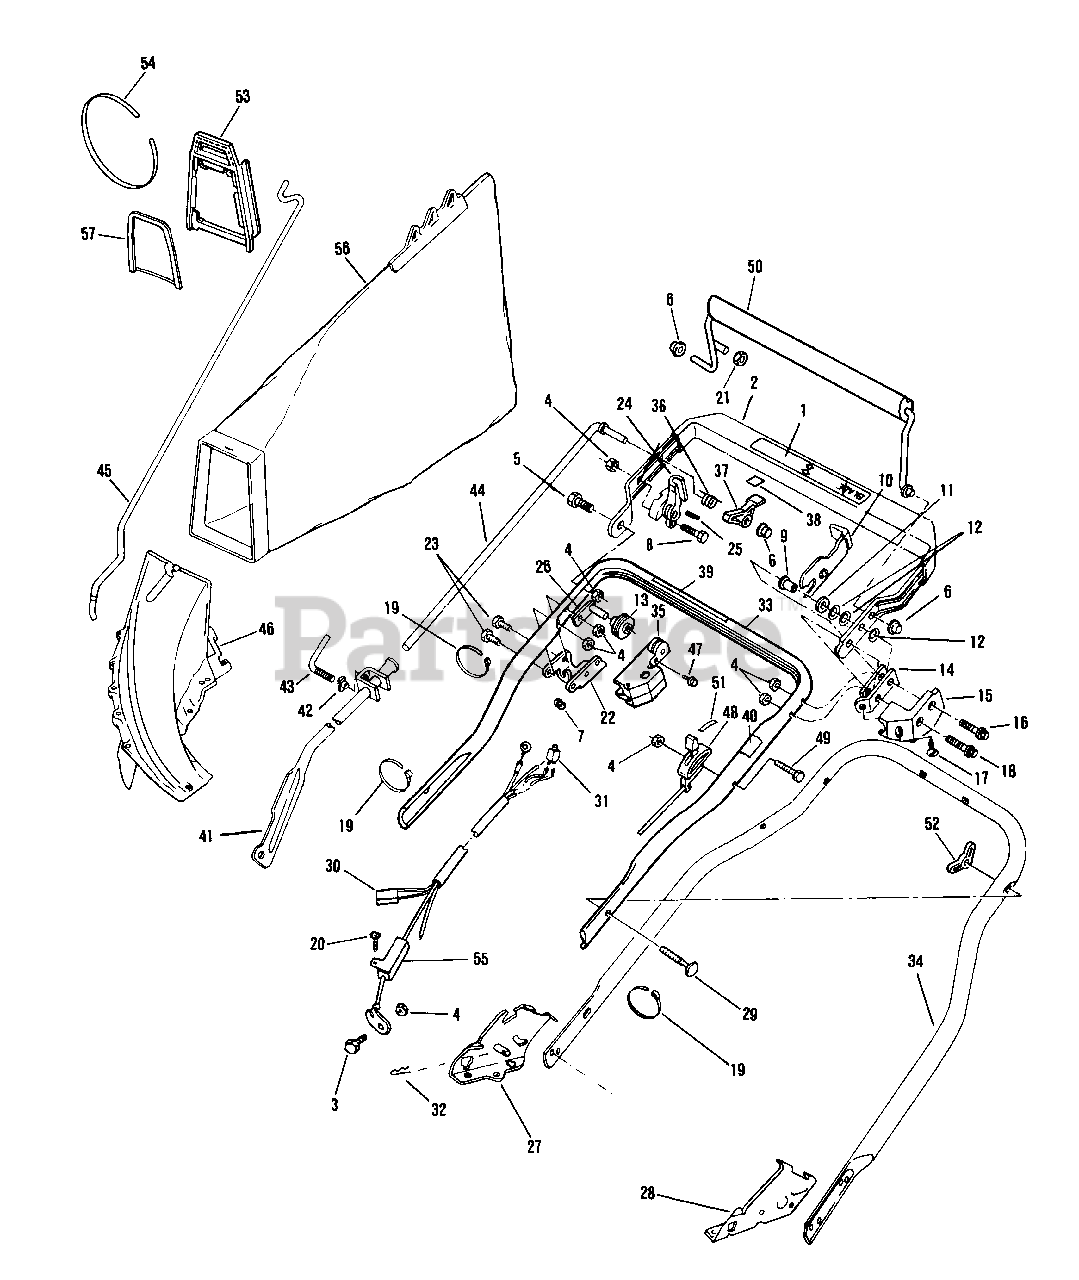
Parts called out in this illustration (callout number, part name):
1	Decal-Engine/Blade Control
2	Top Handle and Doubler Assembly
3	Bolt-Cable to Arm
4	Locknut
5	Bolt-Shoulder-R.H.
6	Pushnut
7	Retaining Ring-Cable
8	Hex-Washer Head Shoulder Bolt
9	Spacer-Flanged
10	Lever-Lockout
11	Washer-Plain
12	Washer-Spring
13	Pulley
14	Down Stop
15	Guard-Lockout
16	Bolt-Shoulder-L.H.
17	Screw-"Tapite"
18	Bolt-Shou Ider
19	Tie Strap
20	Screw-Cable Bracket to Plate
21	Nut-Acorn
22	Bracket-Clutch Cable
23	Screw-Clutch Cable Bracket
24	Cam
25	Roll Pin
26	Pivot-Bracket-Pulley
27	Handle Bracket-R.H.
28	Handle Bracket-L.H.
29	Screw
30	Wire Harness Assembly
31	Switch Assembly
32	Hair Pin-Handle Bracket
33	Handle Section-Center
34	Handle Section-Bottom
35	Case-Switch
36	Spring
37	Stop-Latch Lever
38	Decal-Latch Lever
39	Decal-Starting Instructions
40	Decal-Drive Lockout
41	Control Lever Assembly
42	Nut-Control Lever Clamp
43	Lever-Rod Clamp
44	Rod-Control
45	Grass Rod
46	Chute Assembly
47	Screw-Control Cover
48	Control Assembly-Throttle
49	Screw-Throttle Control
50	Control Lever Assembly
51	Decal-Throttle Control
52	Wingnut
53	Adapter-Bag
54	Strap-Bag
55	Control Cable Assembly
56	Grass Bag
57	Brace-Chute
